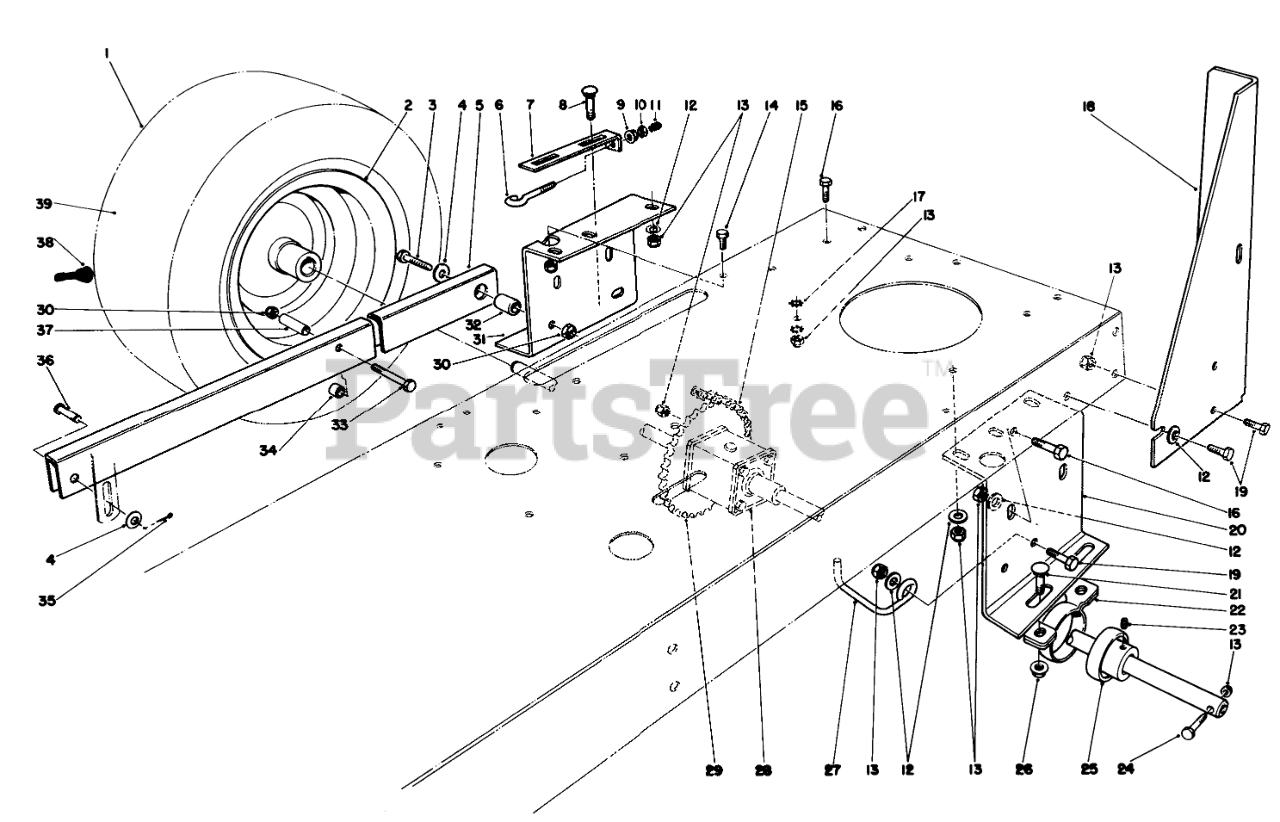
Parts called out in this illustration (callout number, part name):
3	SCREW-HH
4	WASHER-FLAT
5	REAR SUSP ARMR
6	SCREW-ADJUSTING
7	PLATE-ADJUSTING
8	BOLT-CARR
9	NUT-HF
10	NUT-HEX
11	VINYL ROD TIP
12	WASHER-PLAIN
13	NUT-LOCK, NI
14	SCREW-HH
15	ROLLER CHAIN
16	SCREW-HH
17	WASHER-LOCK, INTERNAL
18	LH STANDBAR B
19	SCREW-HH
20	LH REAR AXLE SUPT R
21	BOLT-CARR
22	RTNR-PILLOW BLK
23	SCREW-SET, HSH
24	AXLE MTG BOLT
25	Bearing-Ball (Incl. Ref. #23)
26	NUT-HF
27	BELT GUIDE
28	DIFFERENTIAL
29	42T DIFF SPROCKET
30	NUT-LOCK, CONE
31	RH AXLE SUPPORT R
32	PIN-SUPT ARM
33	SCREW-HH
34	INNER TUBE SPACER
35	PIN-COTTER
36	PIN-CLEVIS
37	OUTER TUBE SPACER
38	STEM-VALVE
39	TUBE-INNER
